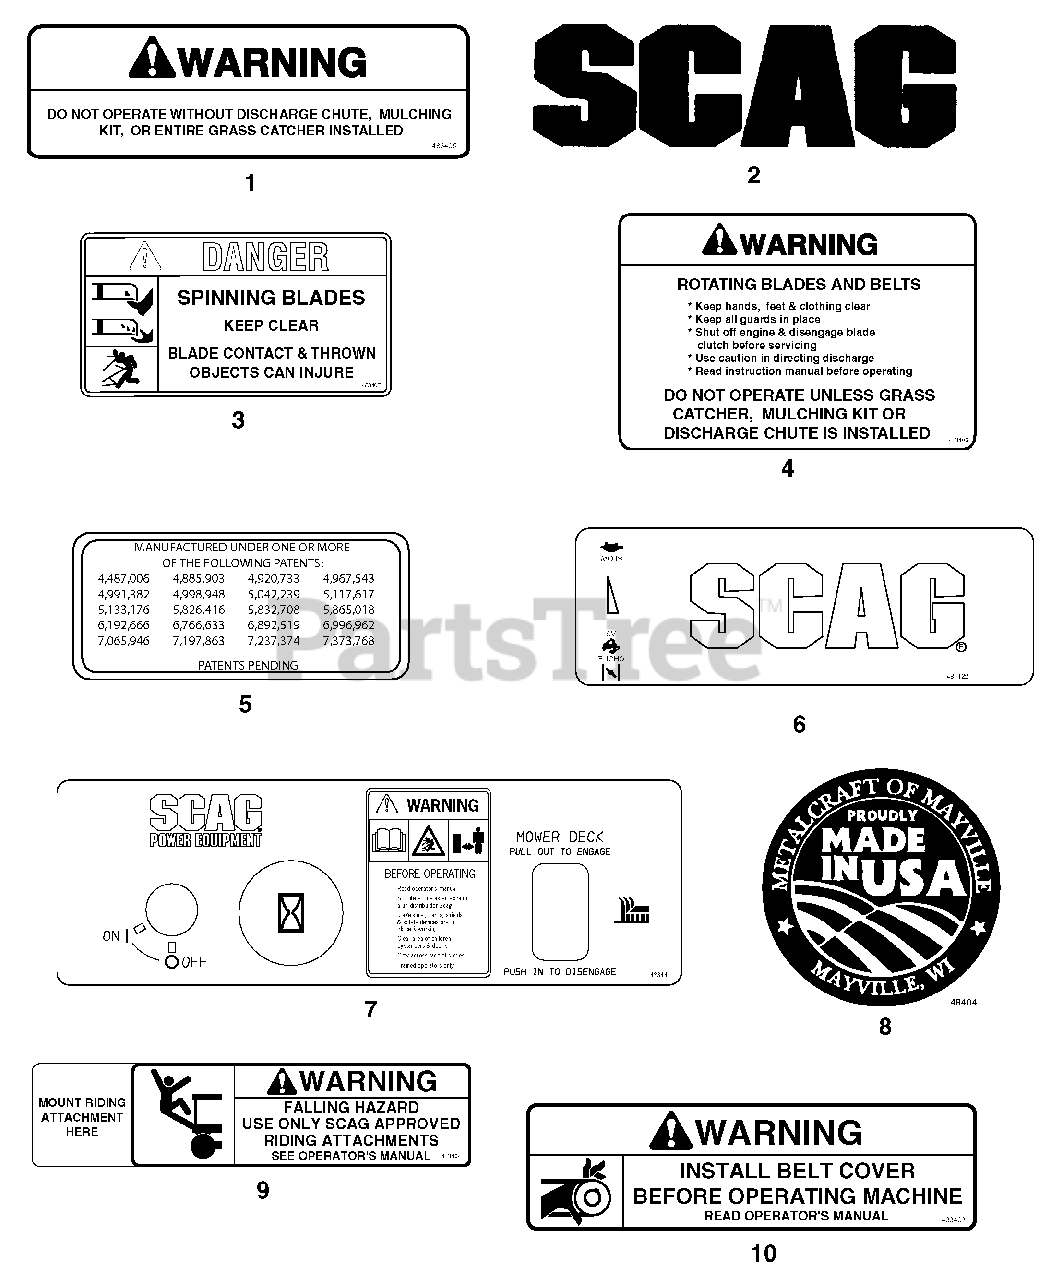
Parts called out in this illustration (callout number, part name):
1	Decal, Discharge Chute
2	Decal, Scag Logo
3	Decal, Danger-Spinning Blades
4	Decal, Warning-Rotating Blades
5	Decal, Patents
6	Decal, Instrument Panel - Front
7	Decal, Instrument Panel - Rear
8	Decal, Metalcraft - Made in USA
9	Decal, Sulky Attachment
10	Decal, Belt Cover
